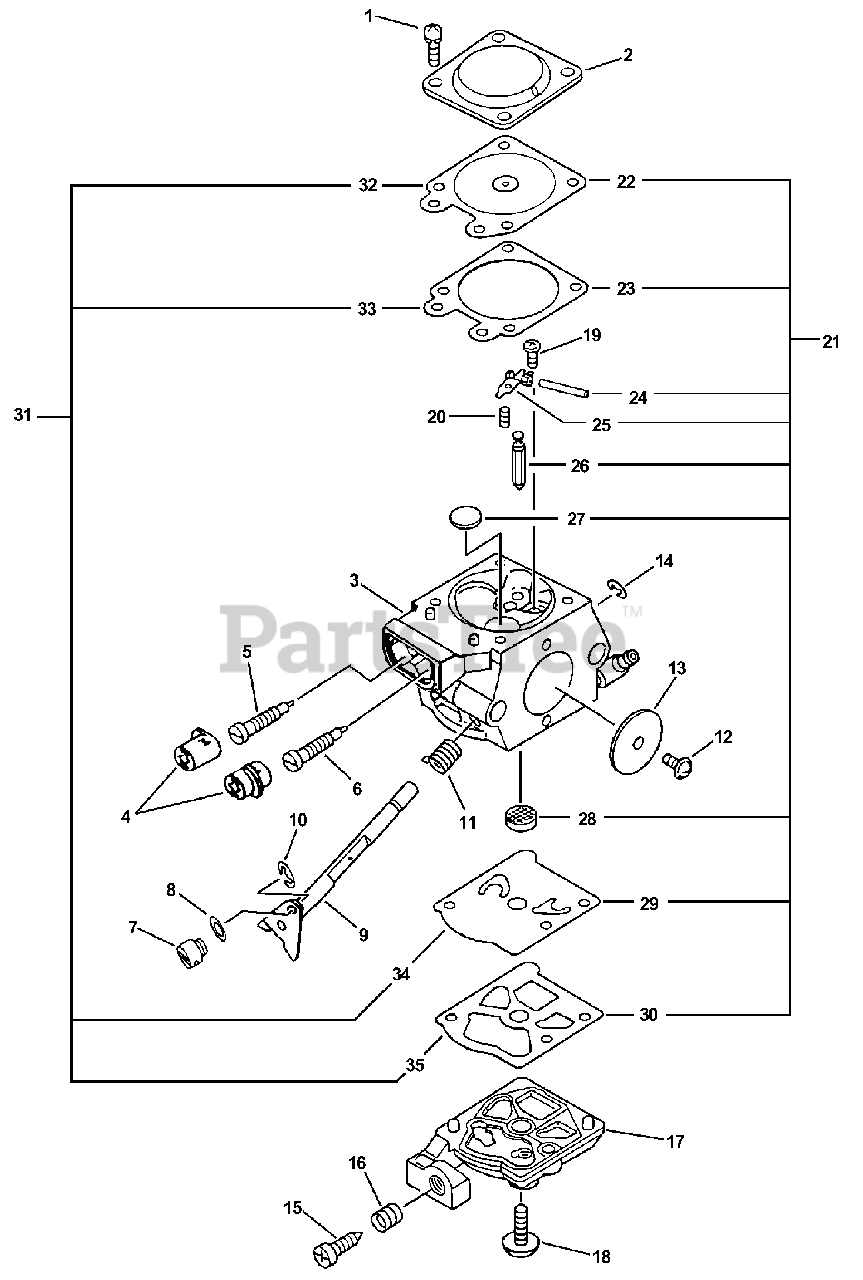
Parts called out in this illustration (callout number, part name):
2	COVER, METERING
3	BODY, CARBURETOR
4	CAP, LIMITER
5	NEEDLE - HIGH SPEED
6	NEEDLE - MIXTURE
9	SHAFT, THROTTLE
10	RING, RETAINING
11	SPRING, THROTTLE RETURN
13	VALVE, THROTTLE
14	RING, RETAINING
15	SCREW, IDLE ADJUST
16	SPRING, IDLE ADJUST
17	COVER, PUMP
18	SCREW, PUMP COVER
19	SCREW, METERING LEVER PIN
20	SPRING, METERING LEVER
21	REPAIR KIT
22	DIAPHRAGM, METERING
23	GASKET, DIAPHRAGM
24	PIN, METERING LEVER
25	LEVER, METERING
26	VALVE, INLET NEEDLE
27	PLUG, WELCH
28	STRAINER
29	DIAPHRAGM, PUMP
30	GASKET, PUMP
31	DIAPHRAGM/GASKET KIT
32	DIAPHRAGM, METERING
33	GASKET, DIAPHRAGM
34	DIAPHRAGM, PUMP
35	GASKET, PUMP
